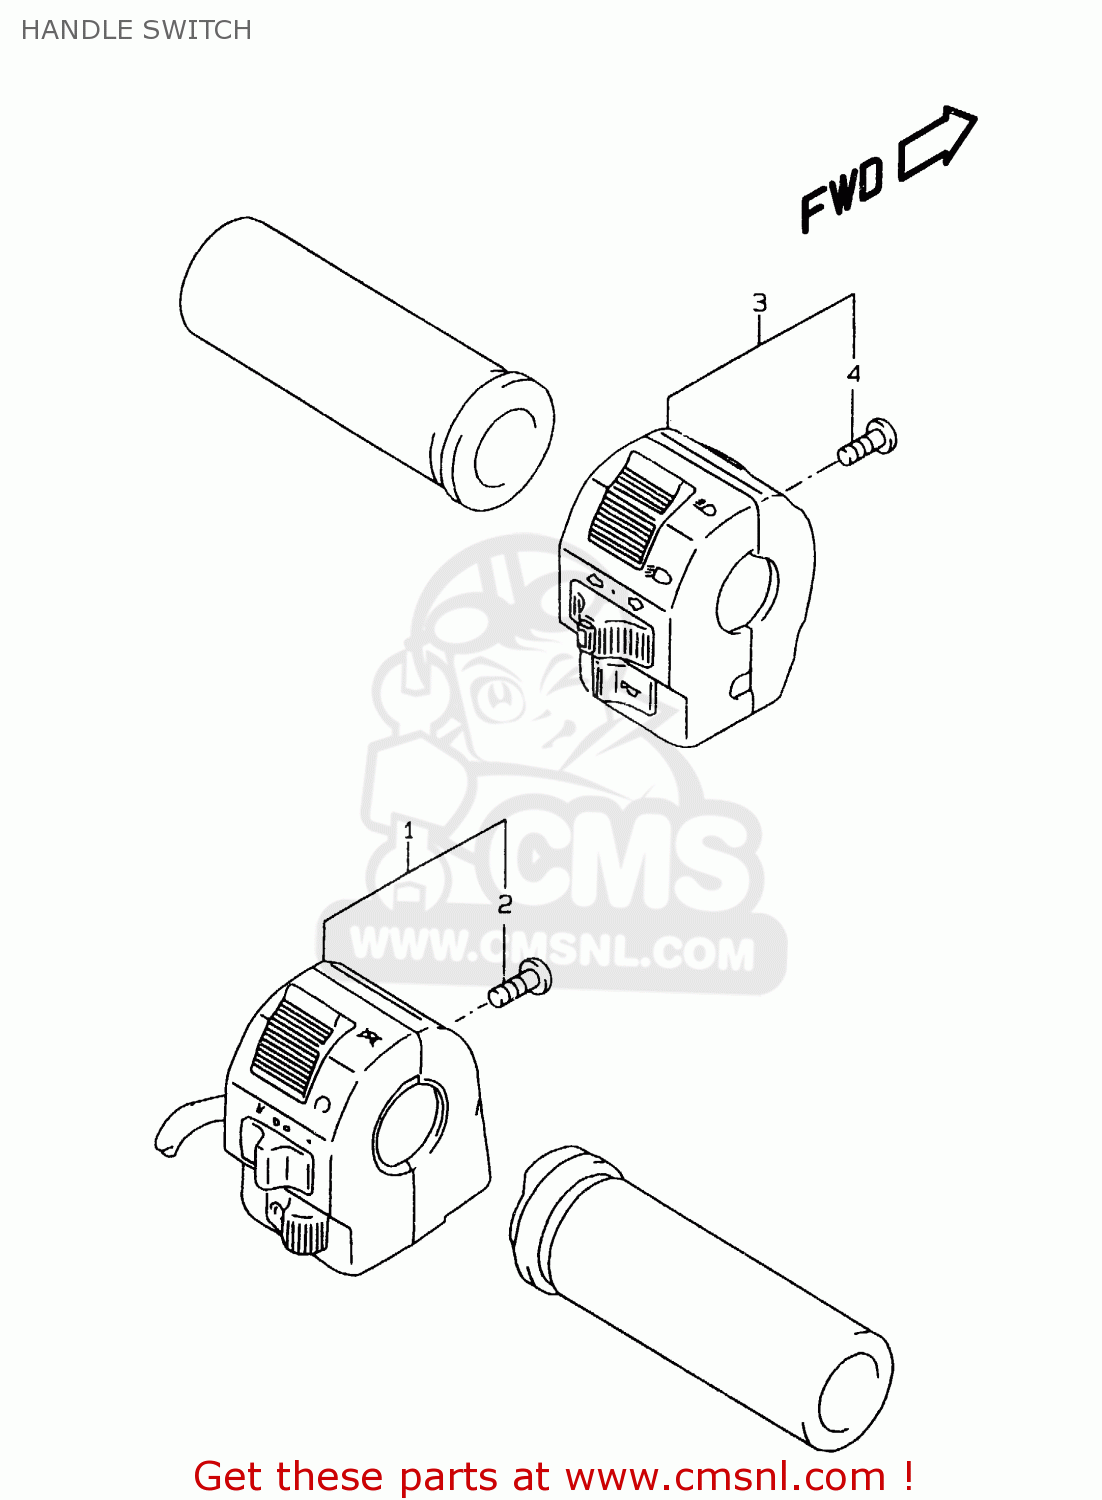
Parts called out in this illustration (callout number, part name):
1	SWITCH ASSY,HANDLE,R
2	SCREW
3	SWITCH ASSY,HANDLE,L
4	SCREW
